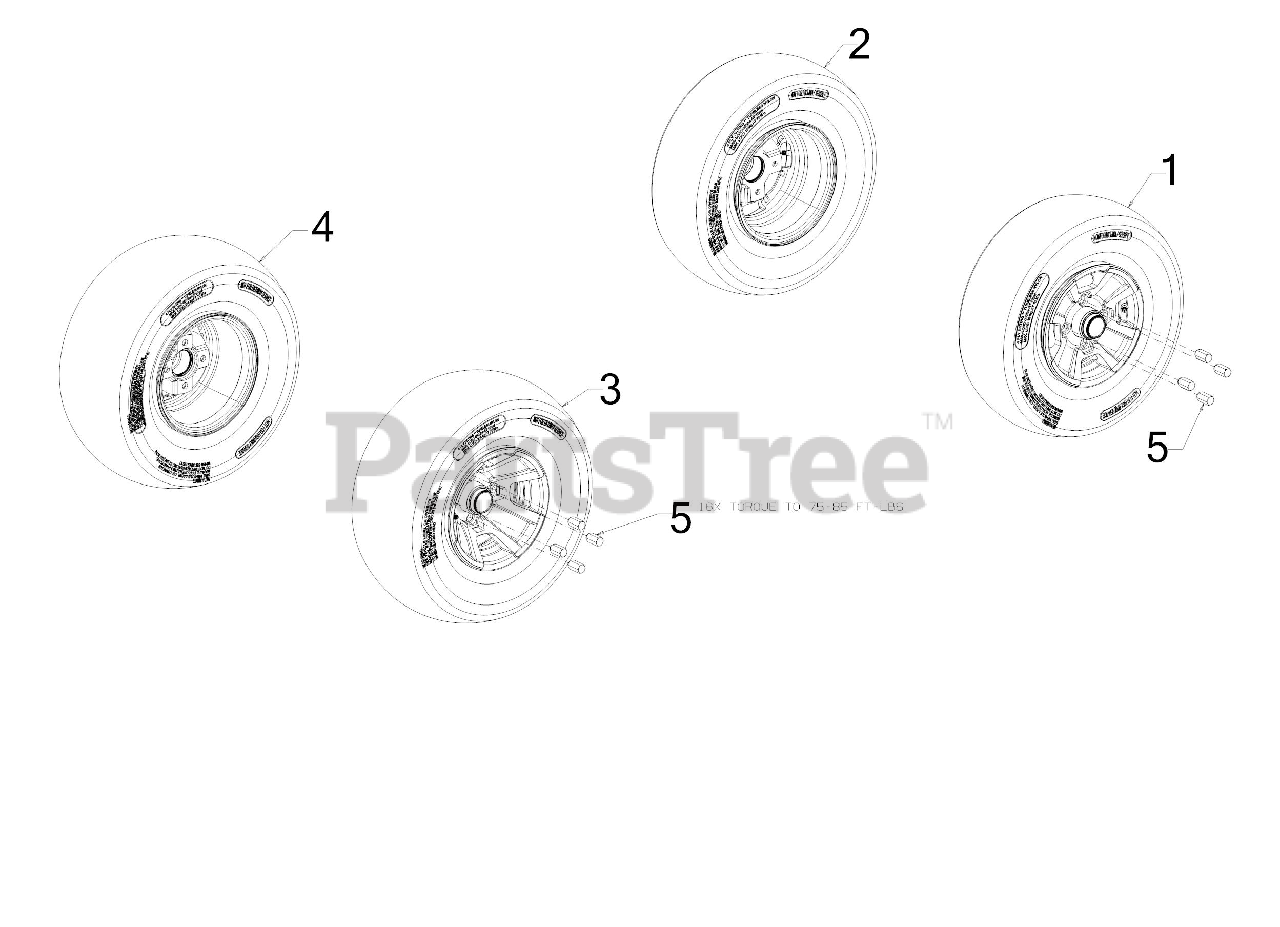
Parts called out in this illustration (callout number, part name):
1	FRONT RIGHT WHEEL ASSEMBLY
2	LEFT FRONT WHEEL ASSEMBLY
3	RIGHT REAR WHEEL ASSEMBLY
4	LEFT REAR WHEEL ASSEMBLY
5	LUG NUT 1/2-20 CHROME
